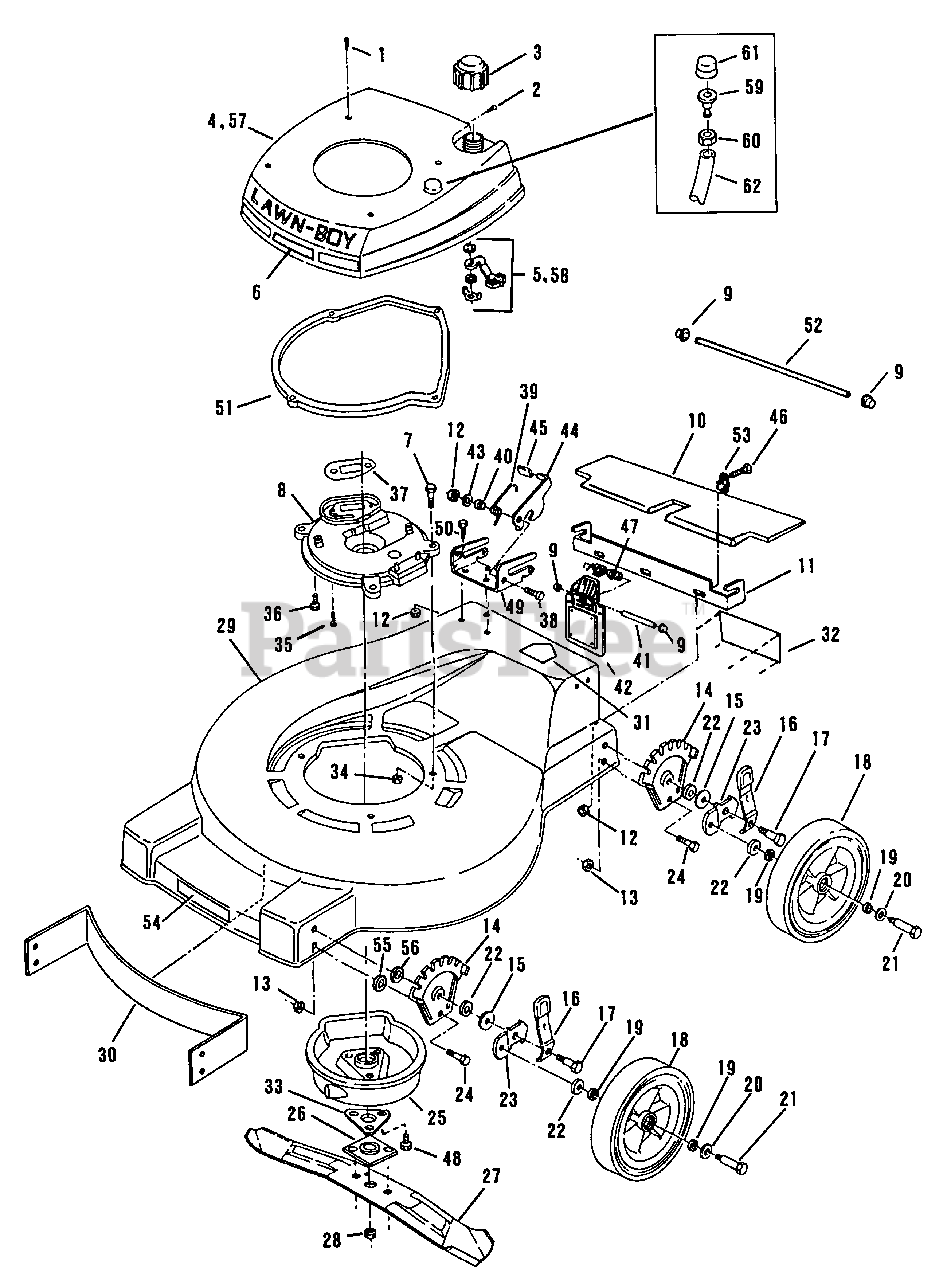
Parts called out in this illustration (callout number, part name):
1	Screw
2	Screw
3	Fuel Cap
6	Decal-Special
7	Screw-Muffler Plate to Housing
8	Plate-Muffler
9	Nut
10	Shield-Trailing
11	Bracket-Bag Hanger
12	Nut-Door Brkt, Bag Latch and Trailing Shield
13	Nut-Height Adjust and Back-up Plate
14	Plate-Height Adjust
15	Washer-Whl. Mtg. Brkt.
16	Knob and Spring Assembly
17	Bolt-Wheel Bracket to Knob and Spring Assembly
18	Wheel and Tire Assembly
19	Washer-Felt
20	Washer-Wheel Bolt Head
21	Bolt-Shoulder-Wheel
22	Washer
23	Bracket-Whl. Ht. Adj.
24	Screw-Ht. Adj. Plate
25	Muffler Cover Assembly
26	Plate and Collar Assembly
27	Blade-20"
28	Nut
29	Housing and Rear Baffle Asy.
30	Baffle-Front
31	Decal-Blade Contact Warning
32	Decal-Caution
33	Support-Crankshaft
34	Nut-Muffler Plate to Housing
35	Screw-Muffler Plt. to Cylinder
36	Screw-Muffler Plt. to Cylinder
37	Gasket-Exhaust
38	Screw-Latch to Bracket
39	Spring-Latch
40	Spacer-Latch to Spring Plate
41	Rod
42	Door Assembly
43	Washer
44	Latch-Bag
45	Knob-Latch
46	Screw-Trailing Shield and Bag Support Bracket
47	Spring
48	Screw-Crankshaft Support
49	Bracket-Rear Bag Mounting
50	Screw-Rear Bag Brk't. Mtg.
51	Spacer-Shroud to Base
52	Rod-Trailing Shield
53	Clamp-Trailing Shield Rod
54	Decal-Headliner
55	Washer
56	Washer
57	Shroud,Tank and Valve Assembly
58	Fuel Valve Assembly
59	Base-Primer
60	Locknut
61	Primer Bulb
62	Tubing-Primer
